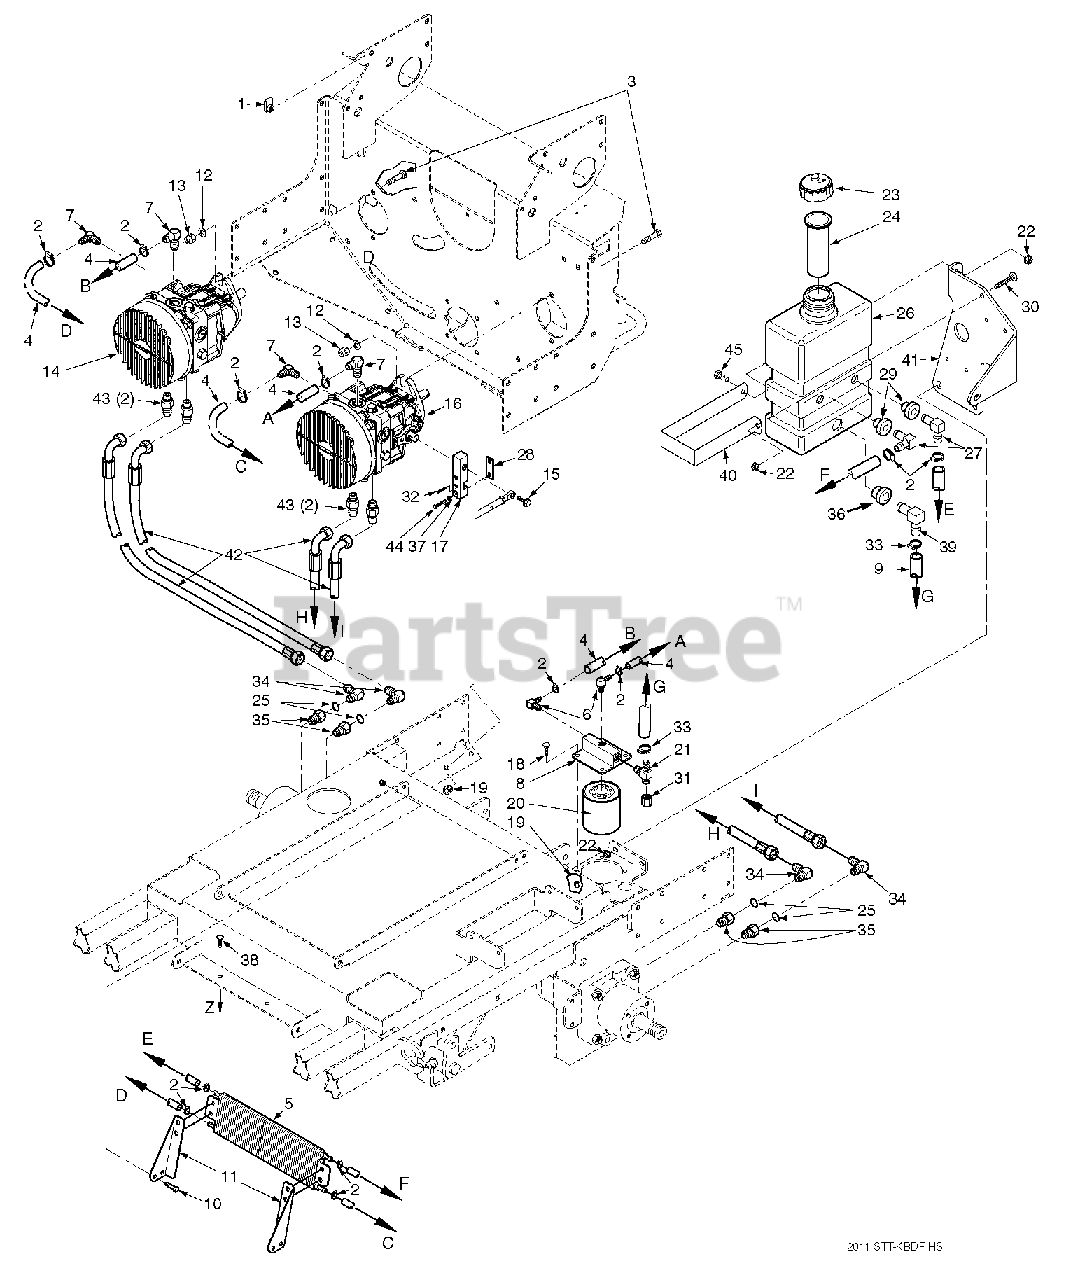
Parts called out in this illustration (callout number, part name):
1	U-Nut 1/4-20
2	Hose Clamp, 0.69" Dia.
3	Bolt, Hex Hd. 3/8-16 x 1-1/2""
4	Hose, 3/8" ID Pushlock
5	Oil Cooler
6	Elbow, 90 Deg. - 1/4" NPT x 3/8" Hose
7	Elbow, 90 Deg. - 9/16" O-ring x 3/8" Hose
8	Oil Filter Base
9	Hose Assy, 1/2" ID
10	Bolt, Hex Hd. 5/16-18 x 3/4"
11	Mounting Bracket - LH, Oil Cooler
12	Flatwasher, 3/8" (.391 x .938 x .105") Grd. 8
13	Nut, Hex Elastic Stop 3/8-16
14	Pump, Right Hand, BDP 16A
15	Bolt, Hex Hd., 3/8-16 x 1-1/4
16	Pump, Left Hand, BDP-16A
17	Block, Pump Control
18	Bolt, Hex Hd. 5/16-18 x 1.0" Zinc
19	Nut, Serr. Flng. 5/16-18
20	Oil Filter
21	Tee, 3/4" O-Ring x JIC x 1/2" Hose
22	Nut, Hex Elastic Stop 1/4-20
23	Cap, Hydraulic Tank
24	Insert, Filler Neck
25	O-Ring
26	Oil Reservoir Assy.
27	Elbow, 90 Deg. 0.38" Hose
28	Clamp Plate, Pump Control
29	Bushing, 0.56" Dia. Viton
30	Screw, Phillips Head, 1/4-20 x 2"
32	Roll Pin, Spring 3/16 x 3/4"
33	Clamp, Hose
34	Elbow, 90 Deg., 5/8 x 1/2"
35	Bushing, 7/8"-14 JIC x 3/4"-16 O-Ring
36	Bushing, 0.78" Dia. Viton
37	Lockwasher, 1/4" Spring
38	Bolt, Carriage 5/16-18 x 3/4"
39	Elbow, 90 Deg.
40	Strap, Hydraulic Tank
41	Support Bracket, Hydraulic Tank
42	Hose Assembly, Pump
43	Union, 5/8 x 1/2
44	Bolt, Hex Head, 1/4-20 x 1-1/4"
45	Bolt, Hex Head, 1/4-20 x 3/4"
